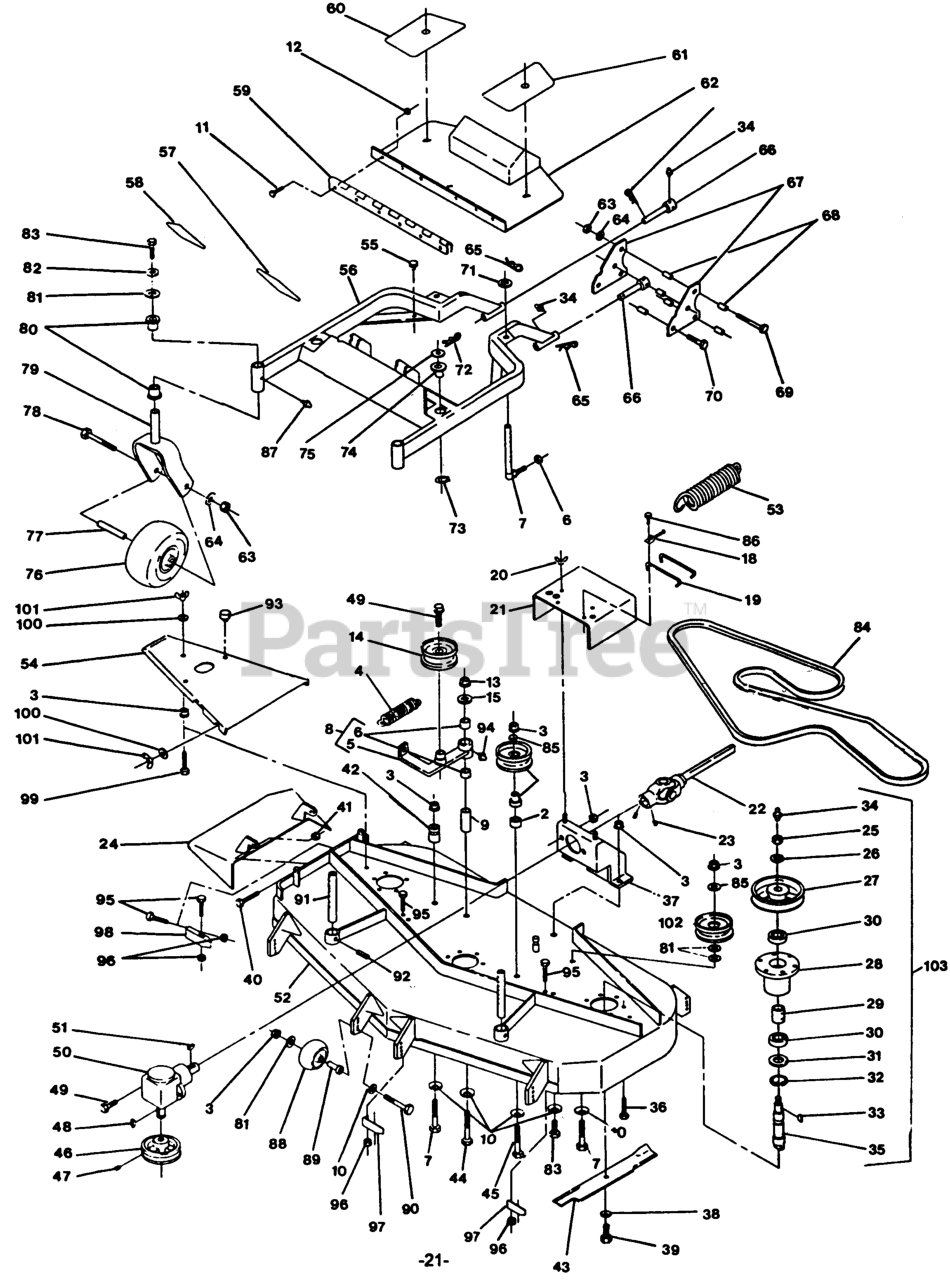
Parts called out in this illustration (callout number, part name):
1	KIT,48 RH IDLER/BUS
4	SPRING,EXTENSION
9	BUSHING
14	IDLER,PULLEY
18	CLIP-DECK, HOLD UP ROD
20	WINGNUT-NYLOCK
22	PTO SHAFT,SHAFT HALF PNT
26	WASHER-SPRING
27	SHEAVE,BLADE DRIVE
29	SPACER,BEARING
31	SEAL,MECHANICAL DUST
32	RING,SNAP WLDS N5000-244
35	SPINDLE-OUTER BLADE
36	SCRW,TPTTE HH
37	WLD,GEARBOX SUPPORT
38	WASHER-SPRING
42	ANCHOR-SPRING PLTD
47	SCREW-SET
50	GEARBOX, PEERLESS
57	PAD,ANTI SKID UPPER LH
58	PAD,ANTI SKID UPPER RH
59	HINGE,FLOORPAN
60	PAD,ANTI SKID LOWER RH
65	PIN,HAIR COTTER
66	PIVOT - MOUNTING, W/ZERK
71	SPACER,REAR DK SUPP PLTD
74	BUSHING-DECK
75	SPACER-CASTER
80	BEARING-FLANGED
86	Pop Rivet, Steel 3/16 X .250
88	ROLLER-SCALP, ANTI
89	BUSHING-ROLLER
91	ROD,DECK SUPPORT
98	WLD,BAFFLE DISCHARGE
101	NUT-WING
102	IDLER,PULLEY
103	CH-52&60 OUTER CUTTR
